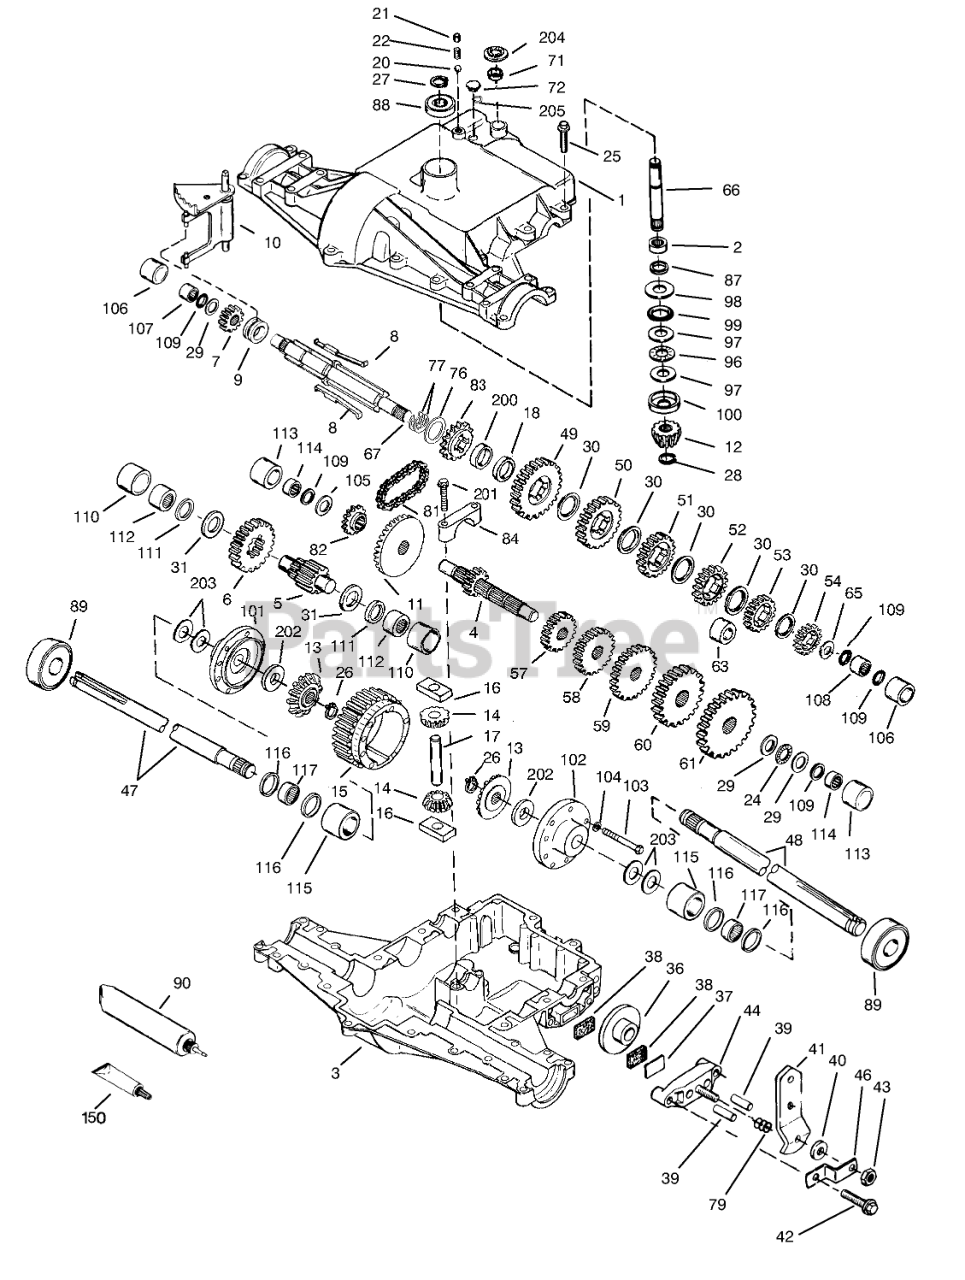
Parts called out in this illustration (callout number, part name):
1	Cover-Transaxle
2	Bearing-Needle
3	Case-Transaxle
4	Countershaft-Gear 9t
5	Shaft-Output
6	Gear-Output 35t
7	Gear-Spur 15t
8	Key-Shift
8	Key-Shift (820-024A Only)
9	Collar-Shift
9	Shift Collar
10	Fork-Shift
10	Fork-Shift (820-024A Only)
11	Gear-Bevel 33t
12	Pinion-Input 13t
13	Gear-Bevel
14	Pinion-Bevel
15	Gear-Ring
16	Biock-Drive
17	Pin-Drive
18	Spacer
20	Ball-Steel
21	Screw-Set
22	Spring
24	Bearing-Thrust
25	Screw 5/16-18x1 1/4
26	Ring-Snap
27	Ring-Snap
28	Ring-Retainer
29	Washer
30	Washer
31	Washer
37	Brake Pad Plate
38	Pad-Brake 2/Pkg
39	Dowel Pin
40	Washer
41	Lever-Brake
42	Ring Set (.020 O S)
43	Locknut
44	Nozzle-Carburetor
46	Bracket
47	Axle 12 9/16" Long
48	Axle 16 7/16" Long
49	Gear-Spur 41t
50	Gear-Spur 35t
51	Gear-Spur 30t
52	Gear Spur 25t
53	Gear Spur 22t
54	Gear Spur 19t
57	Gear Spur 15t
58	Gear Spur 20t
59	Gear Spur 25t
60	Gear Spur 28t
61	Gear Spur 30t
65	Washer
66	Shaft-Input
67	Shaft-Shifter/Brake
67	Shaft-Shifter/Brake (820-024A Only)
71	Cut Seal-Square
72	Plug-Threaded 5/16-18
76	Washer
77	Inverted Retaining Ring
79	Piston ASM (.020 O S)
81	Chain-Roller
82	Sprocket 10t
83	Sprocket (14 teeth)
84	Cap-Bearing
87	Seal Oil
88	Bearing-Ball
89	Bearing-Ball
90	Grease 32 Oz
96	Bearing-Thrust
97	Washer
98	Washer
99	O Ring
100	Washer-Cupped
101	Carrier-Differential
102	Carrier-Differential
103	Screw-Hex Hd.
104	Lockwasher
105	Washer
106	Sleeve
107	Bearing-Needle
108	Bearing-Needle
109	O Ring
110	Sleeve
111	Ring-Square Cut
112	Bearing-Needle
113	Sleeve
114	Bearing-Needle
115	Sleeve
116	Ring-Square Cut
117	Bearing-Needle
150	Gasket Eliminator
200	Spacer
201	Ring Set (.020 O S)
202	Washer
203	Washer
204	Pushnut
205	O Ring
